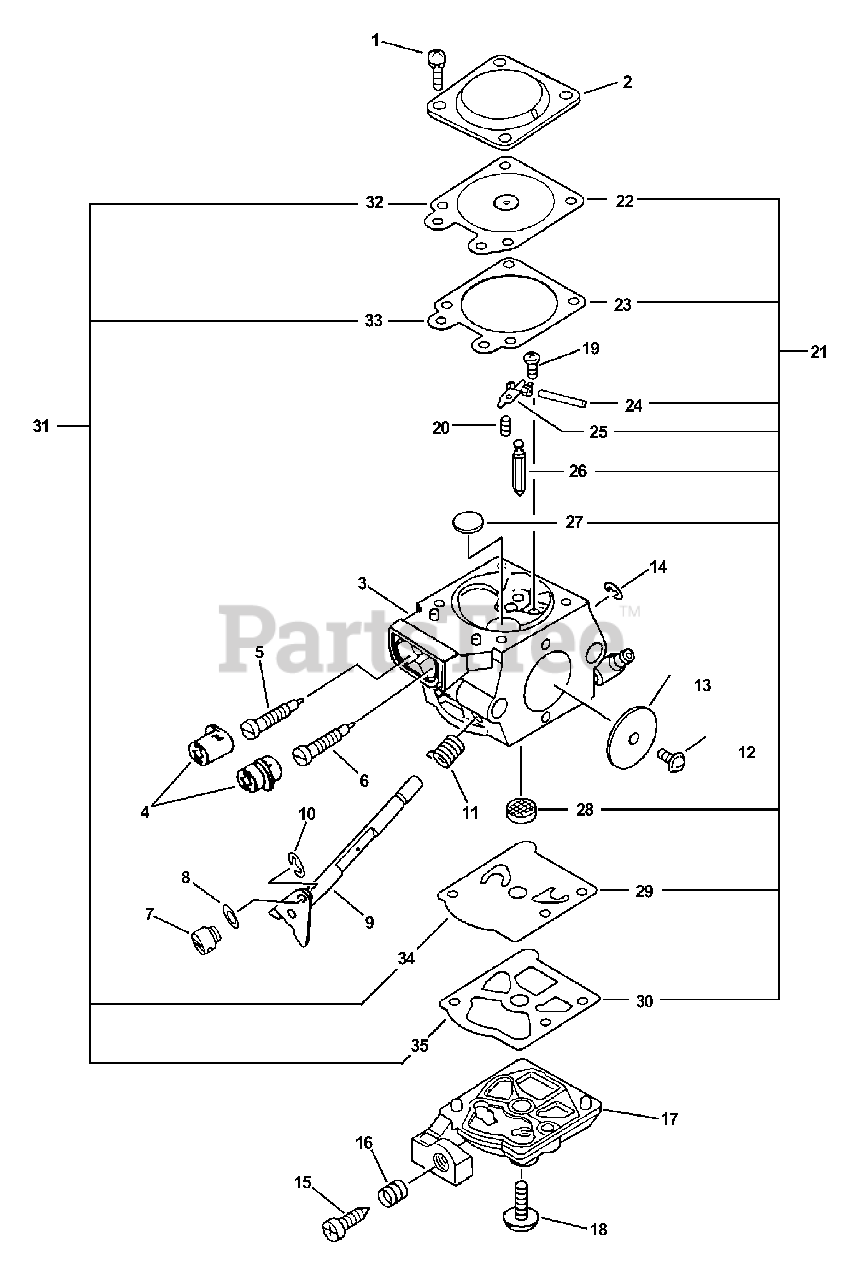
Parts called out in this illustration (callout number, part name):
2	COVER, METERING DIAPHRAGM
3	BODY, CARBURETOR
4	CAP, LIMITER
5	NEEDLE, HIGH SPEED
6	NEEDLE, MIXTURE
9	SHAFT, THROTTLE
11	SPRING, THROTTLE RETURN
13	VALVE, THROTTLE
15	SCREW, IDLE ADJUST
16	SPRING, IDLE ADJUST
17	COVER, FUEL PUMP
19	SCREW, METERING LEVER PIN
20	SPRING, METERING LEVER
21	REPAIR KIT, CARBURETOR
22	DIAPHRAGM, METERING
23	GASKET, DIAPHRAGM
24	PIN, METERING LEVER
25	LEVER, METERING
26	VALVE, INLET NEEDLE
27	PLUG, WELCH
28	STRAINER
29	DIAPHRAGM, PUMP
30	GASKET, PUMP
31	GASKET / DIAPHRAGM KIT
32	DIAPHRAGM, METERING
33	GASKET, DIAPHRAGM
34	DIAPHRAGM, PUMP
35	GASKET, PUMP
